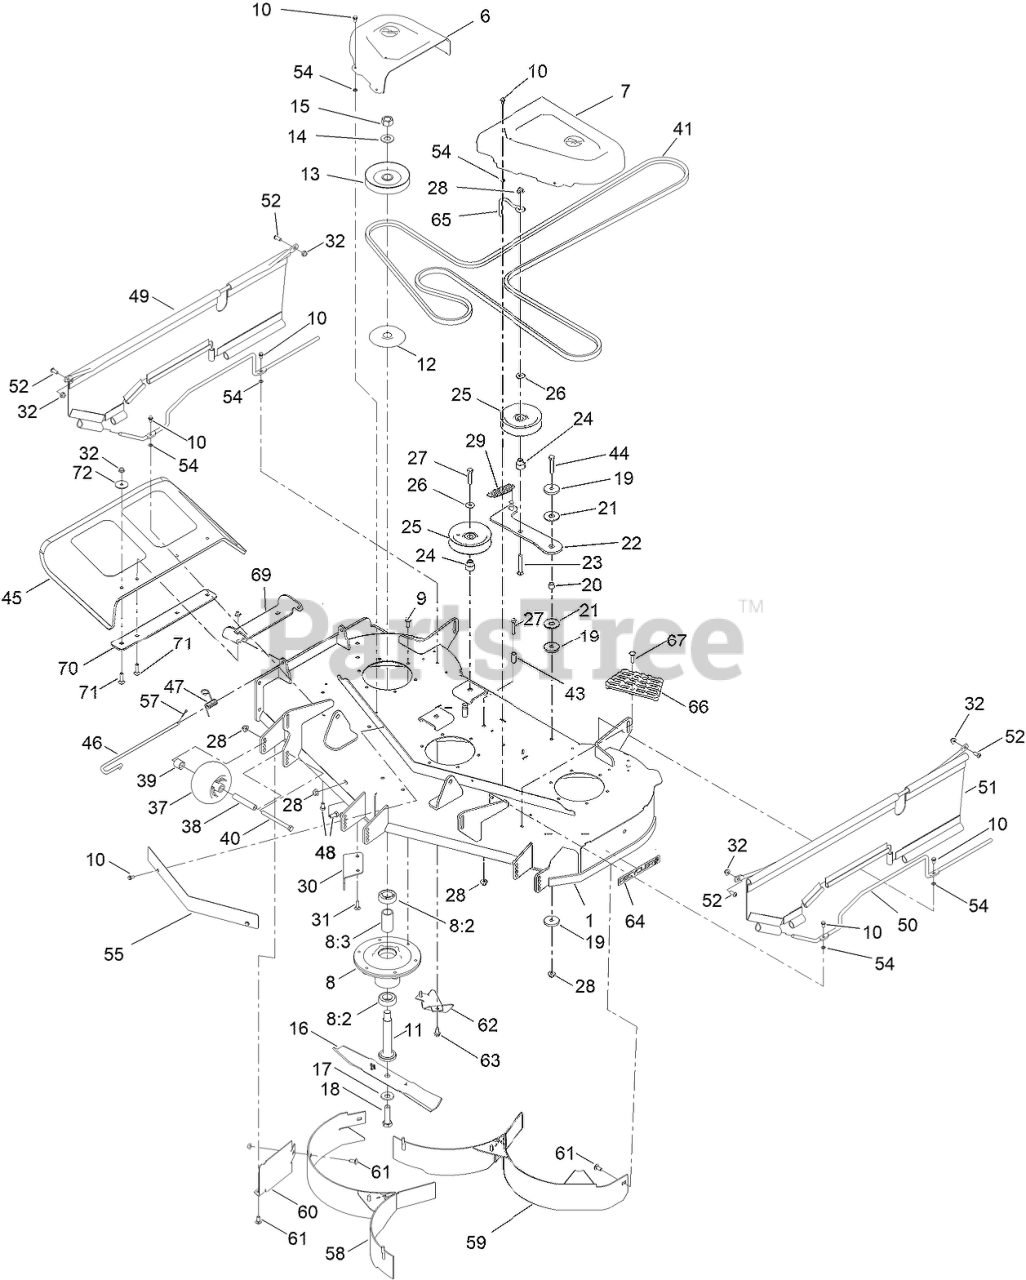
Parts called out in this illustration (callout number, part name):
1	48in DECK ASM
6	COVER-BELT, RH
7	COVER-BELT, LH
8	SPINDLE ASM
8:2	BEARING-BALL
8:3	SPACER-BEARING
9	SCREW-TAPTITE
10	SCREW-HWH
11	SHAFT-SPINDLE
12	SHIELD-BEARING
13	PULLEY
14	WASHER
15	NUT-HEX
16	BLADE-MULCH, 16.50 INCH
17	WASHER-BELLEVILLE
18	SCREW-BLADE
19	WASHER-PLAIN
20	SPACER
21	WASHER-FRICTION, COMPOSITE
22	IDLER ARM ASM
23	SCREW-CARR
24	BUSHING-IDLER
25	PULLEY-IDLER, FLAT
26	WASHER-HARDENED
27	SCREW-HH
28	NUT-HF, NI
29	SPRING-EXTENSION
30	BAFFLE-CUTOFF
31	SCREW-CARR
32	NUT-HF
37	ROLLER-SCALP, ANTI
38	TUBE-SPANNER
39	SPACER-AXLE, REAR
40	SCREW-HH
41	V-BELT
43	SPACER-FENDER
44	HHCS 3/8-16 X 2, GR5, CZ
45	DEFLECTOR
46	PIN-CHUTE
47	SPRING-TORSION
48	SCREW-HH
49	ROD SUPPORT, UPPER
50	ROD SUPPORT, LOWER
51	SIDE GUARD ASM
52	SCREW-HSBH
54	NUT-RETAINING
55	SHIELD-FRONT
57	PIN-COTTER
58	BAFFLE-RECYCLER
59	BAFFLE-RECYCLER
60	GUARD-BAFFLE
61	BOLT-CARR
62	KICKER-FLANGED
63	SCREW-HWHTF
64	DECAL-RECYCLER
65	GUIDE-BELT, IDLER
66	STEP-DECK
67	BOLT-CARRIAGE
69	BRACKET-DEFLECTOR, UPPER
70	PLATE-DEFLECTOR
71	BOLT-CARRIAGE
72	WASHER-FLAT
